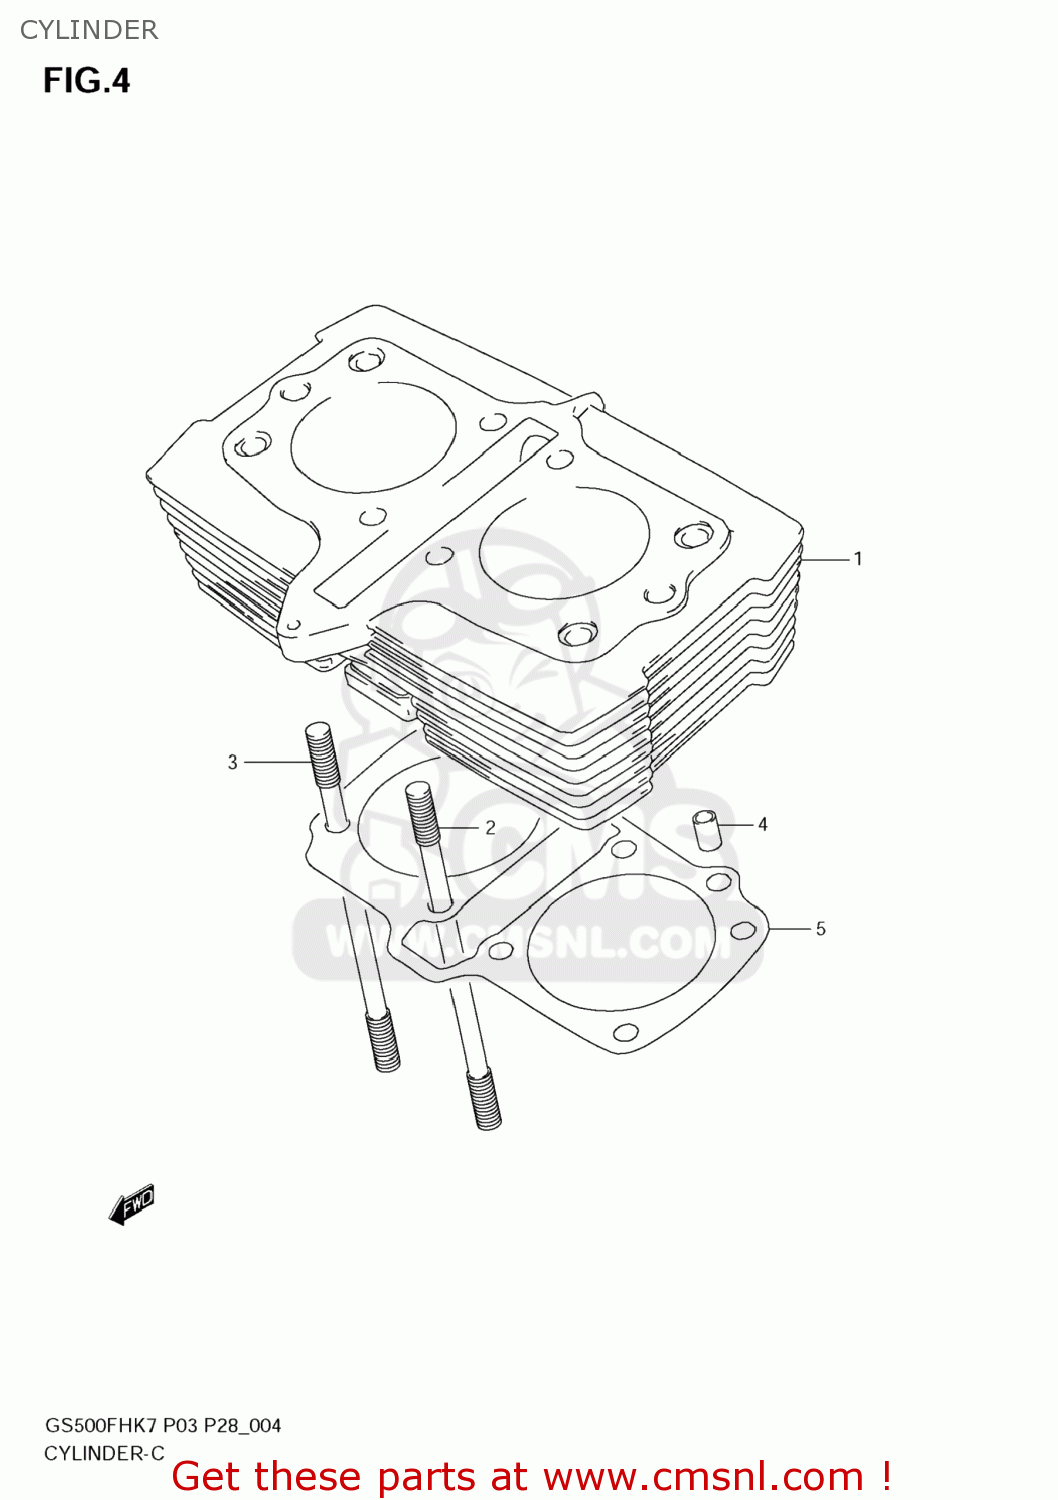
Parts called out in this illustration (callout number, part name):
1	CYLINDER
2	BOLT,STUD
3	BOLT,STUD
4	PIN
5	GASKET,CYLINDER (NAS)
